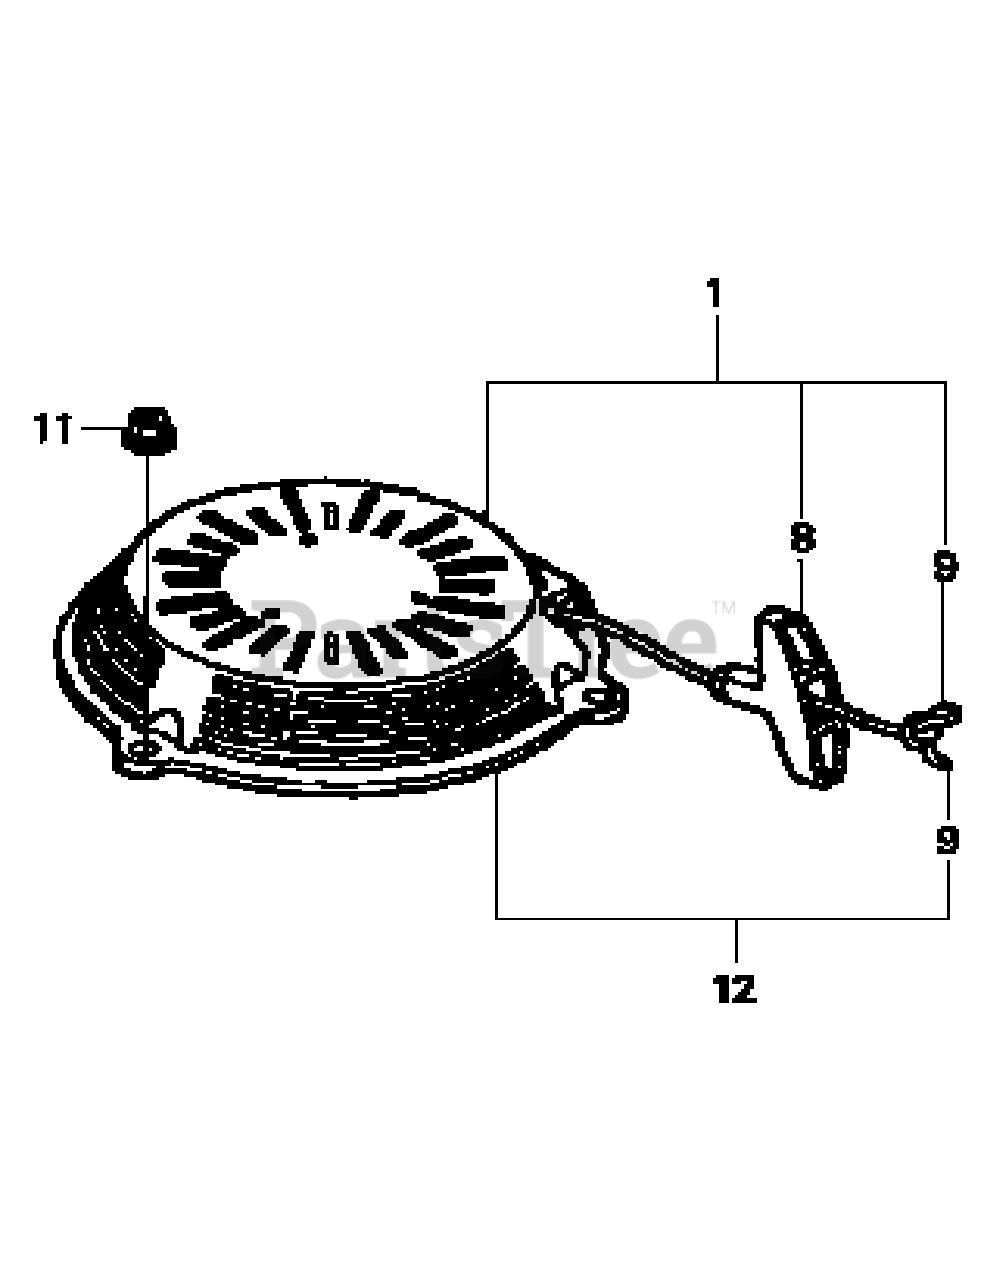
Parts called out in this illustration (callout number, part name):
1	Recoil Starter Assy.
8	Recoil Starter Knob
9	Rope (#3.5 x 52")
11	Flange Nut (6mm)
